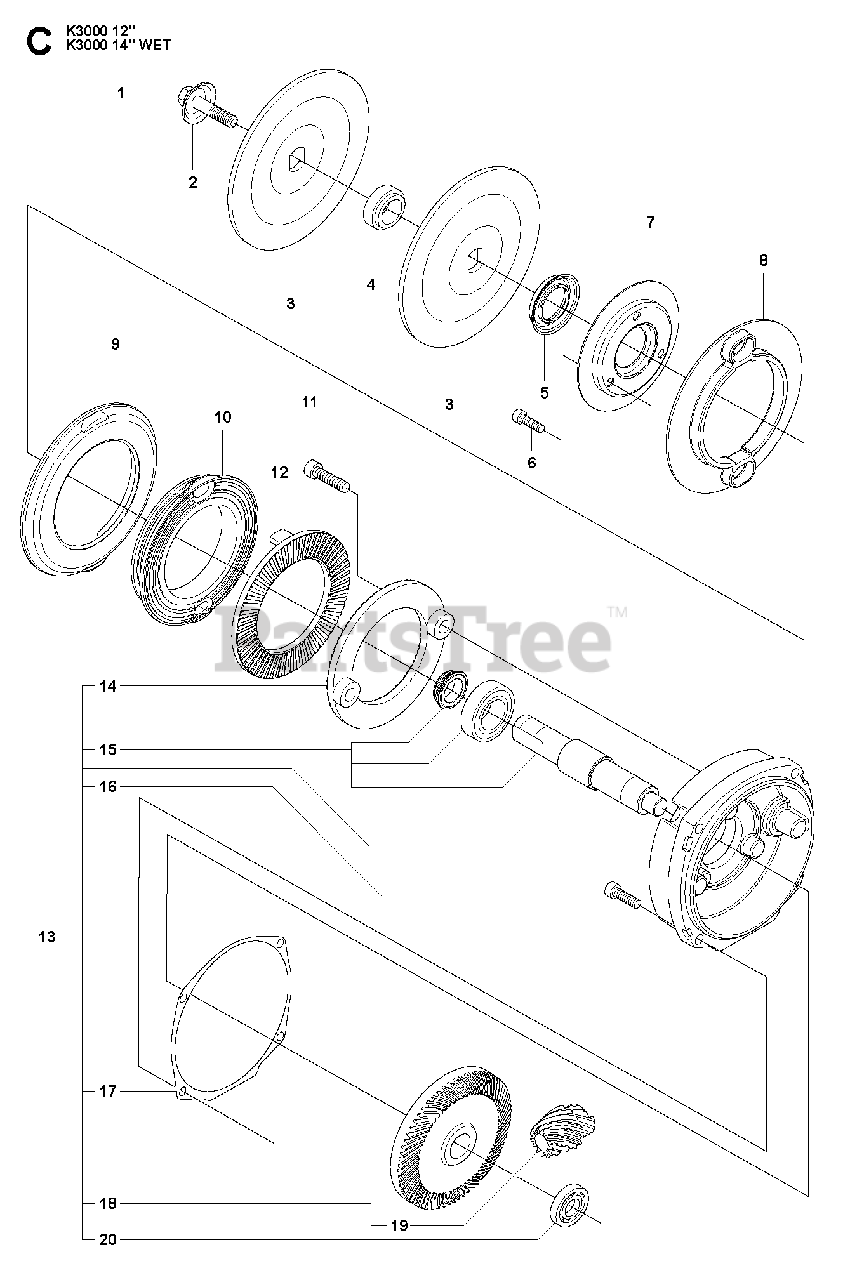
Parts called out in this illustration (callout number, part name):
3	FLANGE WASHER
4	KITDiam 20mm
4	KITDiam 22,2mm
4	KITDiam 25,4mm
4	BUSHINGDiam 30,5mm
6	SCREW ITXSCM
8	SPACER RING"12"" only"
9	SPACER RING"12"" only"
11	SCREW ITXSCM
13	GEAR SETIncl. 14 - 18, 20
15	SHAFT
16	SCREW ITXSCM
17	GASKET
18	GEAR WHEELIncl. 19
20	BALL BEARING
